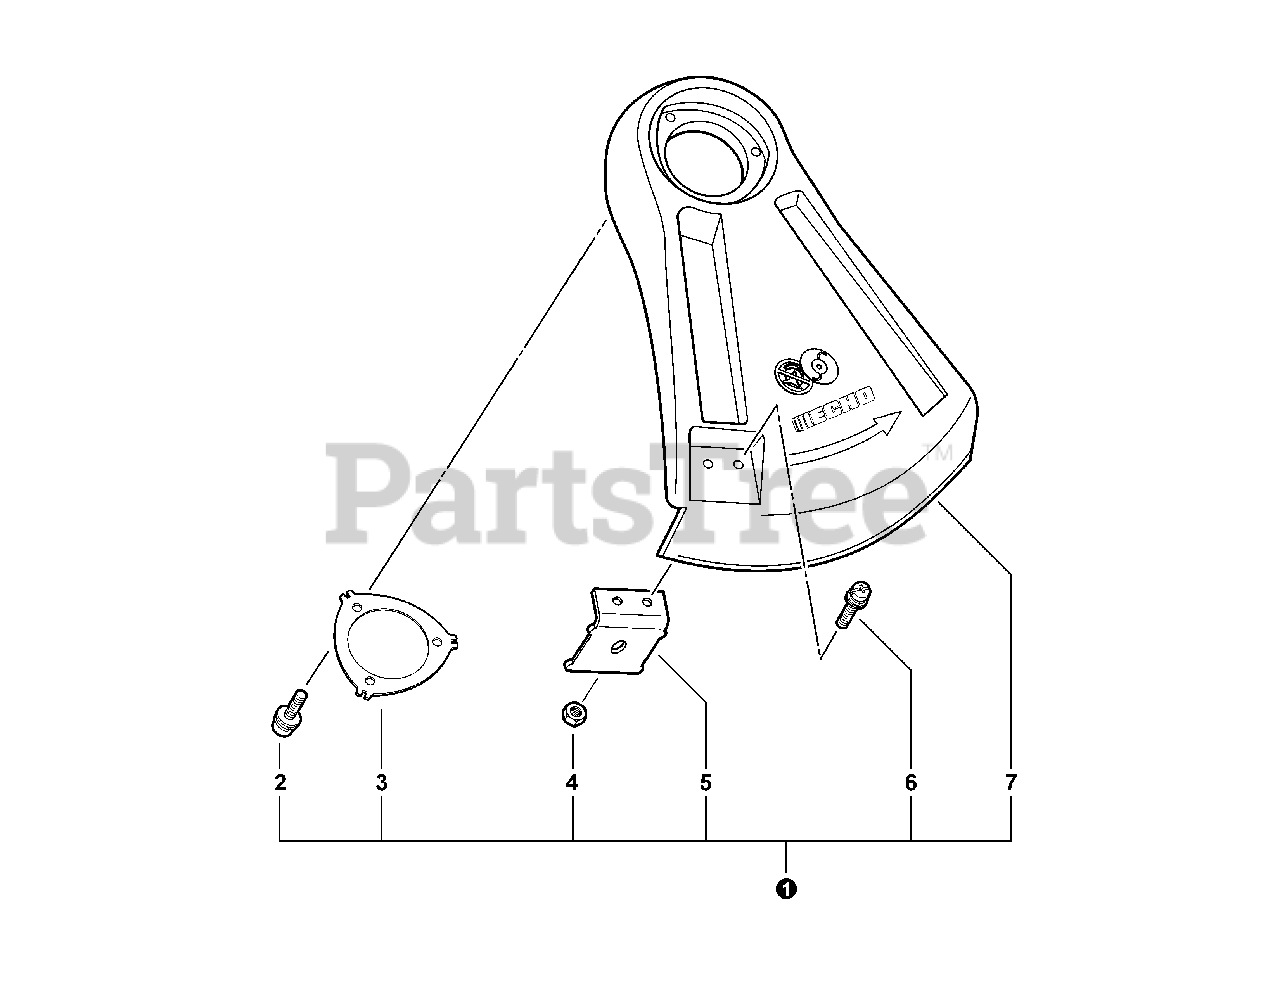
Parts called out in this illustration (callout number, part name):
1	DEBRIS SHIELD KIT - PLASTIC
2	SCREW - 5×16
3	PLATE, SHIELD
5	KNIFE,TRIMMER LINE
6	SCREW - 5×16
7	SHIELD, DEBRIS - PLASTIC
